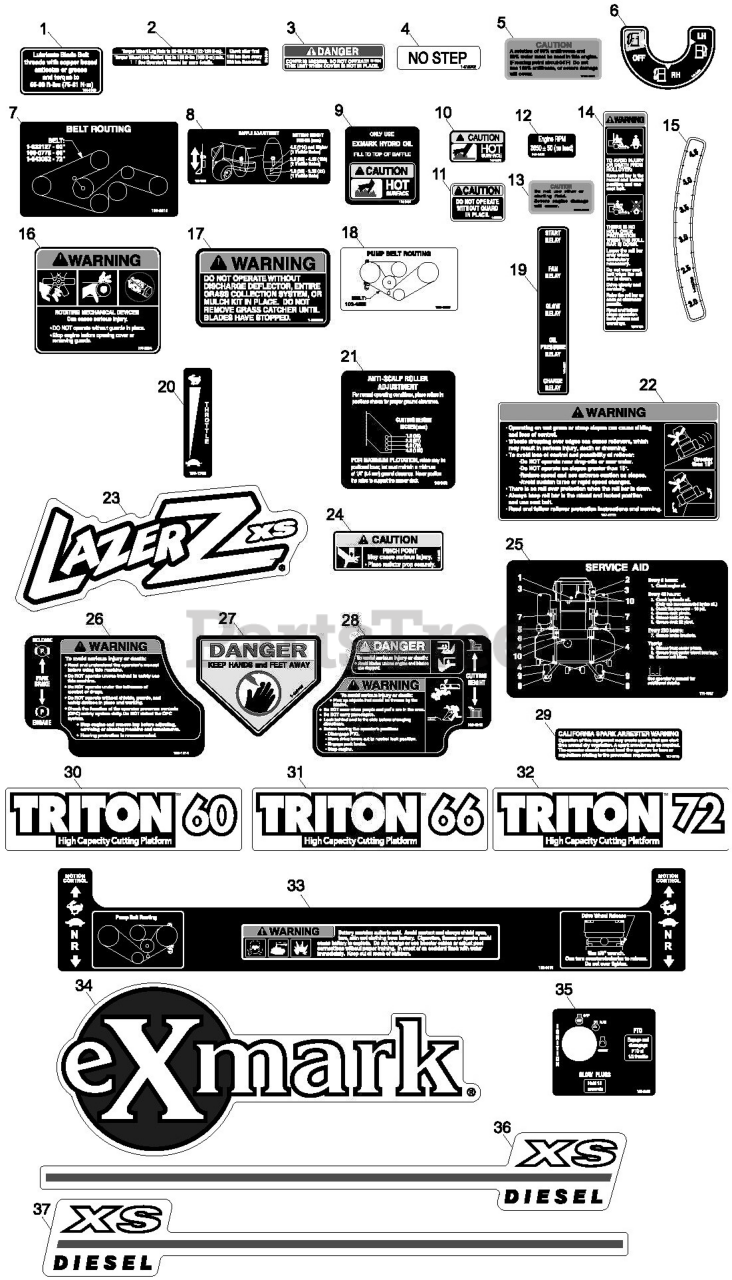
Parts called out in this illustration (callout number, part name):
1	DECAL,BOLT TORQUE
3	DECAL-COVER, MISSING
4	DECAL,NO STEP
5	DECAL-ANTIFREEZE
6	DECAL-VALVE, FUEL
7	DECAL,BELT ROUTING
8	DECAL,BAFFLE ADJUSTMENT
9	DECAL-HYDRAULIC TANK
10	DECAL-CAUTION
11	DECAL-GUARD
13	DECAL-CAUTION
14	DECAL-WARNING, FOLDING RO
15	DECAL-HEIGHT, DECK
16	DECAL,WARNING
17	DECAL-WARNING, DISCHARGE
18	DECAL,HYDRO BELT ROUTING
19	DECAL,RELAY KUBOTA
20	DECAL,THROTTLE ONLY
21	DECAL,ANTISCALP
22	DECAL-WARNING
23	DECAL,LAZER XS MODEL
24	DECAL,RADIATOR ASSEMBLY
25	DECAL, CHECK SERVICE
26	DECAL,PARK BRAKE
27	DECAL-DANGER
28	DECAL,DECK HEIGHT
29	DECAL-ARRESTER, SPARK
30	DECAL,TRITON 60
31	DECAL,TRITON 66
32	DECAL,TRITON 72
33	DECAL-CONSOLE, TOP
34	DECAL,EXMARK
35	DECAL,IGNITION,GLOW,PTO
36	DECAL,HOOD LXS DIESEL RH
37	DECAL,HOOD LXS DIESEL LH
